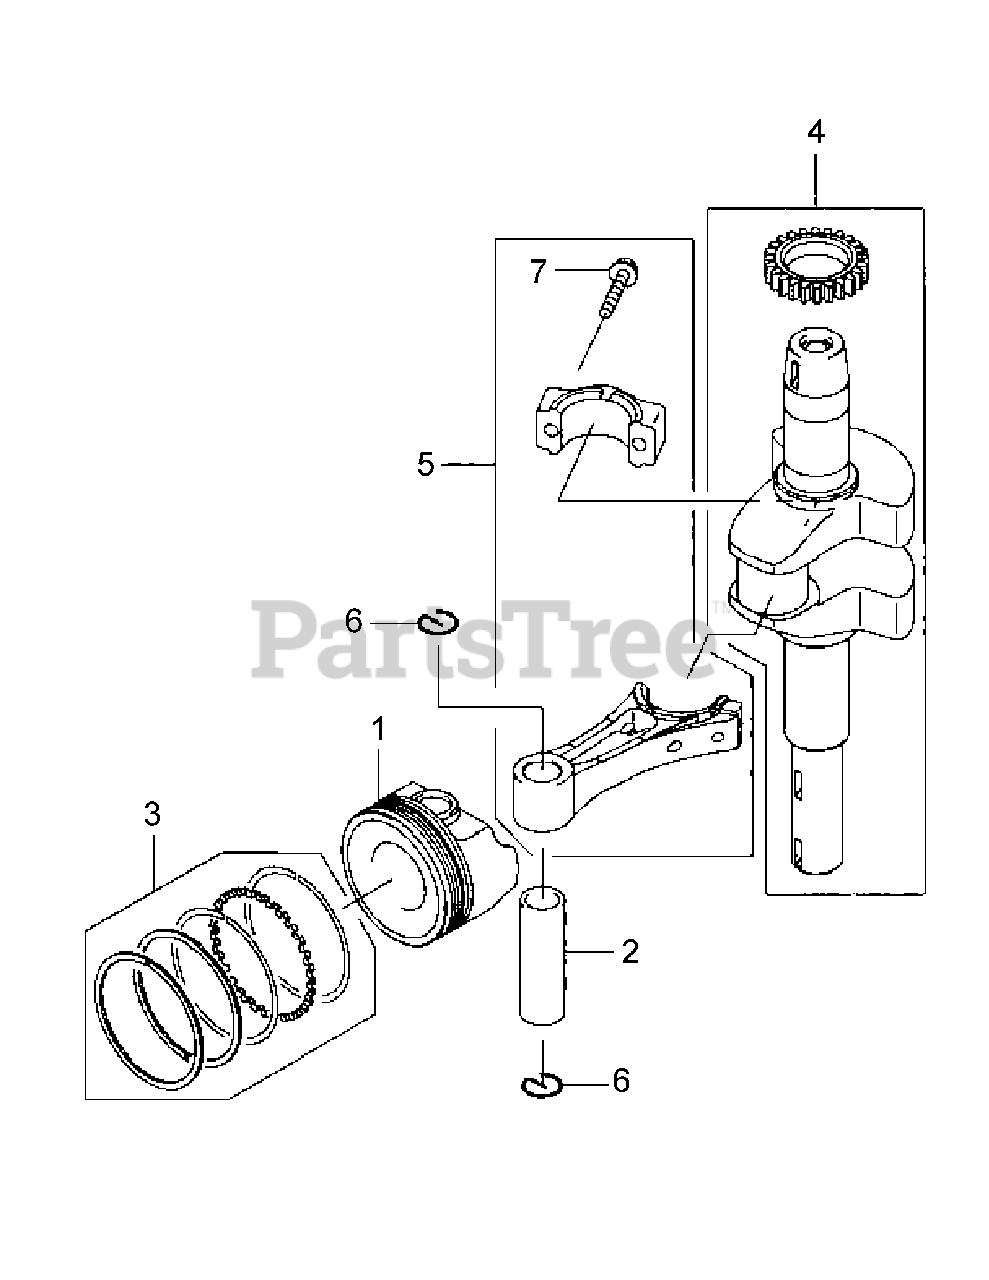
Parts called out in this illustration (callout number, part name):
1	Piston
3	Piston Ring Set
4	Crankshaft With Gear
5	Connecting Rod Assy.
